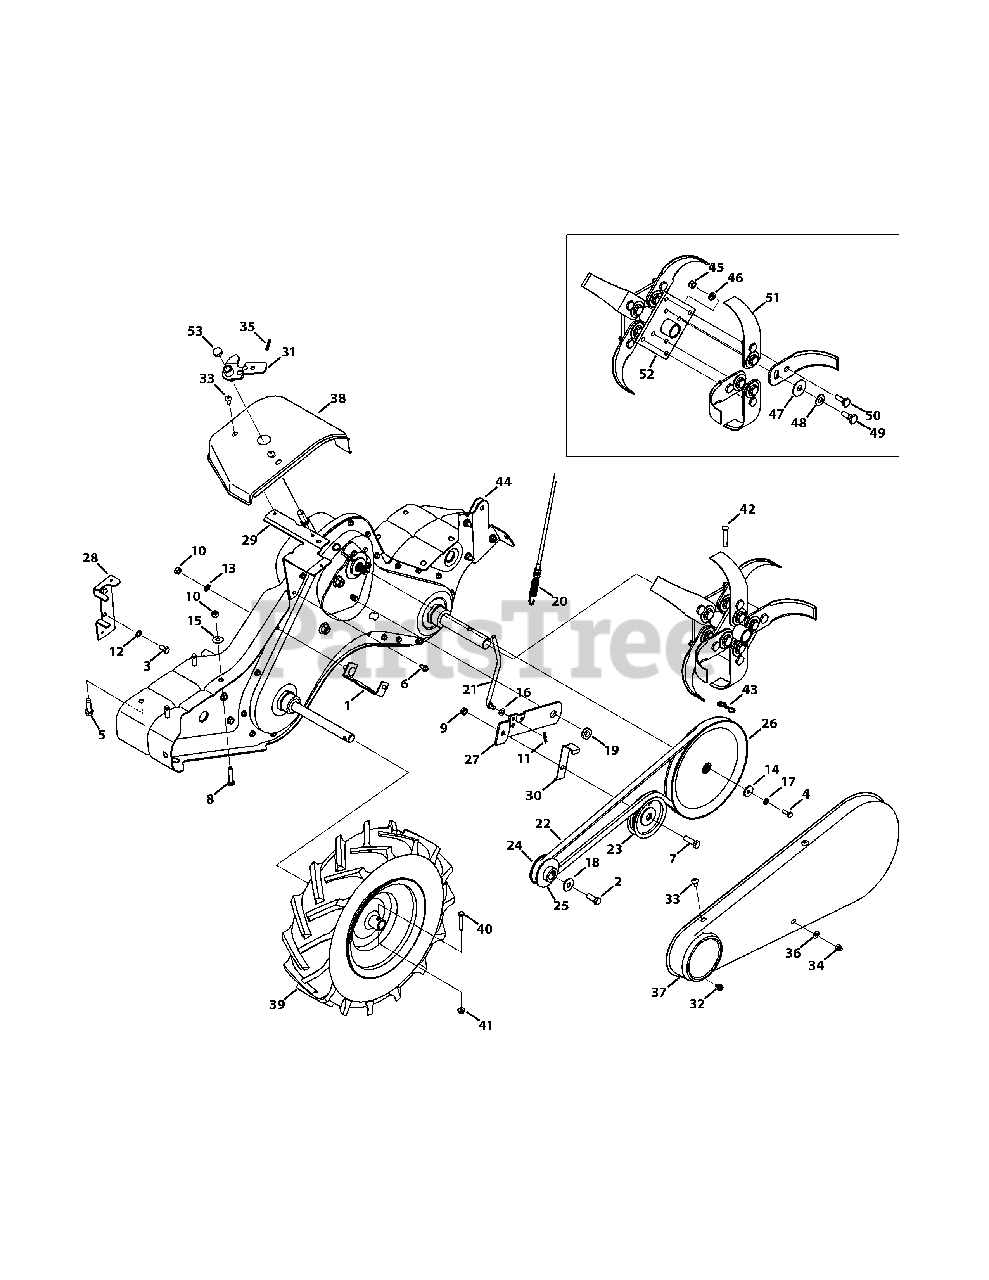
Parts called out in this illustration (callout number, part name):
1	Belt Cover Bracket Assembly
2	Hex Head Screw, 3/8-24 x 1.00
3	Hex Head Screw, 5/16-24 x .625
4	Hex Head Screw, 1/4-28 x .75
5	Screw, 3/8-16 x 1.250
6	Screw, 1/4-20 x 0.500
7	Hex Head Screw, 3/8-16 x 1.25
8	Hex Head Screw, 5/16-18 x 1.50
9	Jamlock Nut, 3/8-16
10	Hex Nut, 5/16-18
11	Cotter Pin, .072 DIA. x 1.13 LG
12	Washer, Lock, 5/16
13	Washer, Lock, 5/16
14	Washer, Flat, .265 x .938 x .120
15	Washer, Bell, .340 x .872 x .060
16	Washer, Spring, .317 x .625 x .020
17	Washer, Lock, 1/4
18	Washer, Bell, .396 x 1.140 x .095
19	Shoulder Nut, 7/16-20
20	Clutch Cable
21	Idler Pulley Rod
22	Belt, 4L x 58.16 LG
23	Flat Idler Pulley w/ Flanges, 3.75 O.D.
24	Engine Pulley, Inner Half
25	Engine Pulley, Outer Half
26	Input Pulley, 4L x 8.594
27	Idler Pulley Bracket
28	Belt Keeper Bracket, B&S 6.5 HP
29	Shift Cover Bracket
30	Idler Belt Keeper
31	Shift Crank Assembly
32	Screw, 1/4-20:0.375
33	Screw, 1/4-14:0.625
34	Lock Nut, Cap, 1/4-28
35	Spiral Pin, 3/16 x 1.00
36	Washer, Flat, .271x .630 x .065
37	Belt Cover
38	Shift Cover
39	Wheel, 16 x 4.6 x 8
40	Hex Head Screw, 1/4-20 x 1.50
41	Flangelock Nut, 1/4-20
42	Clevis Pin, .375 x 1.75
43	Cotter Pin, Bow-Tie
44	Complete Gear Case Assembly
45	Hexlock Nut, 3/8-24
46	Washer, Lock, 3/8
47	Washer, Flat, .51 x 1.5 x 0.07
48	Washer, Bell, .525 x 1.00 x .050
49	Screw, Shoulder, 3/8-24 x 1/2 x .325
50	Screw, Shoulder, 3/8-24 x 1/2 x .180
51	Articulating Tine
52	Tine Adaptor Assembly
52	Tine Assembly
